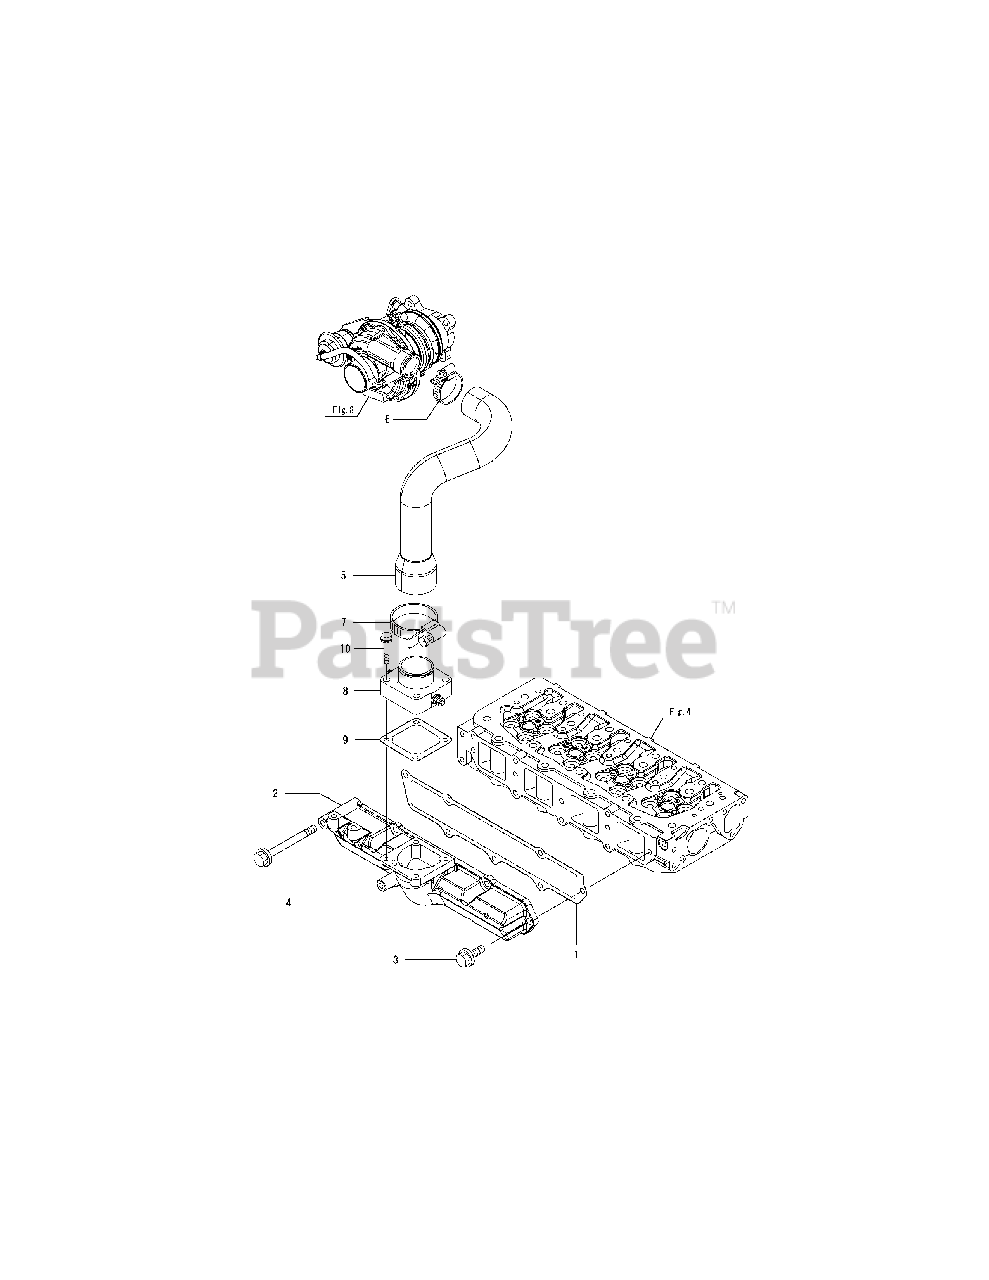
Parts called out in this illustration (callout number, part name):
1	GASKET, MANIFOLD
2	MANIFOLD, AIR INTAKE
3	BOLT M 8X 20 PLATED
4	BOLT M 8X 80 PLATED
9	GASKET, AIR HEATER
10	BOLT M 8X 35 PLATED
